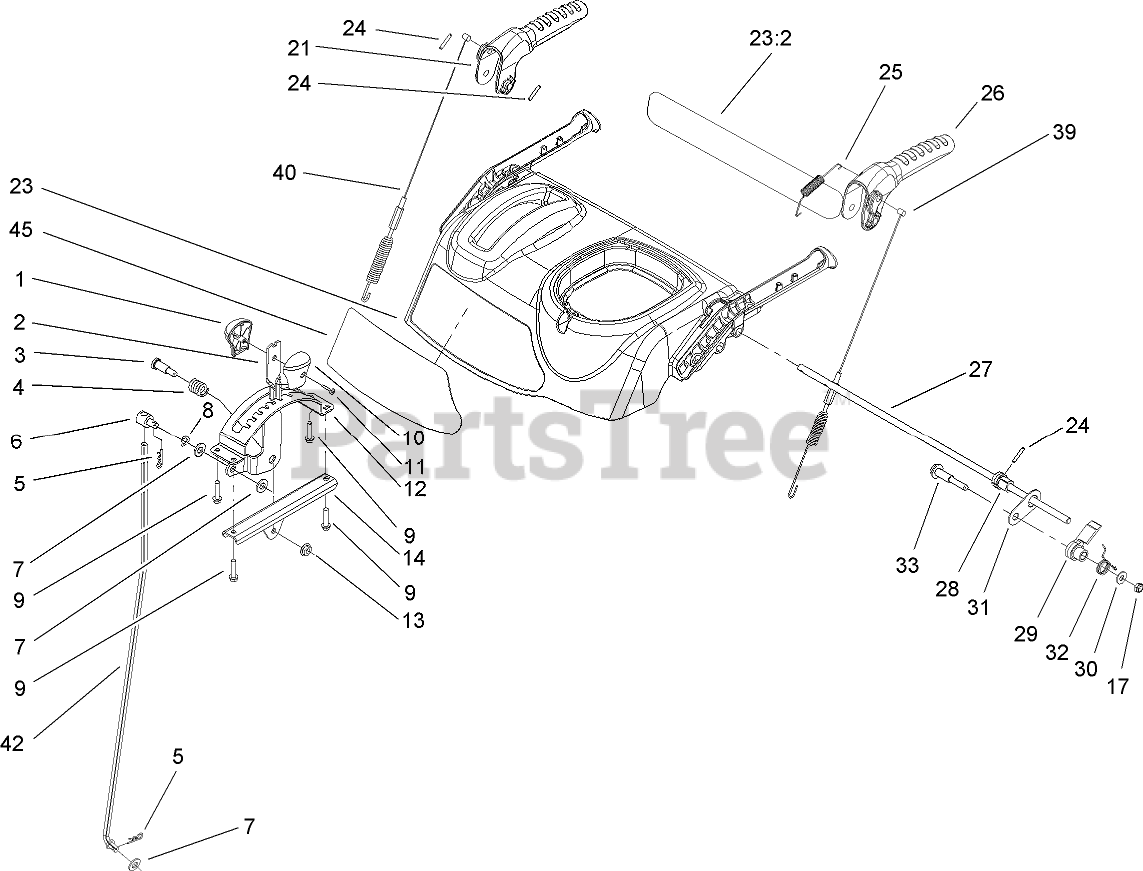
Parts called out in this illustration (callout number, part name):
1	KNOB-SHIFT, RH
2	SELECTOR-SPEED
3	SCREW-SHOULDER
4	SPRING-COMPRESSION
5	PIN-COTTER
6	TRUNNION
7	WASHER-FLAT
8	WASHER-SPRING
9	SCREW-PLASTITE
10	KNOB-SHIFT, LH
11	SCREW-PPH
12	GUIDE-SELECTOR, SPEED
13	NUT-HF
14	MOUNT-SELECTOR, SPEED
17	NUT-LOCK, NI
21	LEVER-AUGER
23	CONTROL PANEL ASM
23:2	DECAL-PANEL, BACK CONTROL
24	PIN-SPRING
25	SPRING-TENSION
26	LEVER-TRACTION
27	ROD-LOCKOUT
28	CAM-LOCKOUT
29	LATCH-LOCKOUT
30	WASHER-FLAT
31	LINK-LOCKOUT
32	SPRING-TORSION
33	SCREW-SHOULDER
39	CABLE-TRACTION
40	CABLE-AUGER
42	ROD-SHIFT
